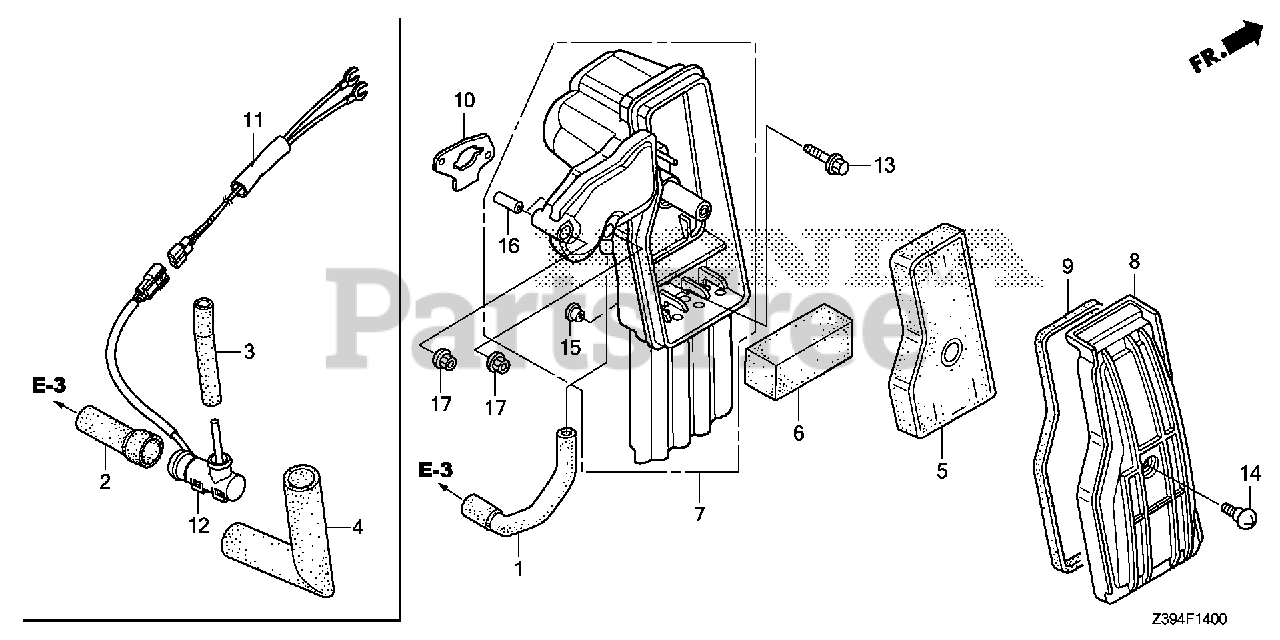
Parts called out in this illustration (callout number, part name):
1	TUBE, BREATHER
5	ELEMENT, AIR CLEANER
6	FILTER (OUTER)
7	HOUSING, AIR CLEANER
8	COVER, AIR CLEANER
9	SEAL A, AIR CLEANER COVER
10	GASKET, AIR IN. JOINT
13	BOLT, FLANGE (5X16)
14	SCREW, SPECIAL (6X16)
15	COLLAR, REFLECTOR SETTING
16	COLLAR, AIR CLEANER
17	NUT, FLANGE (5MM)
